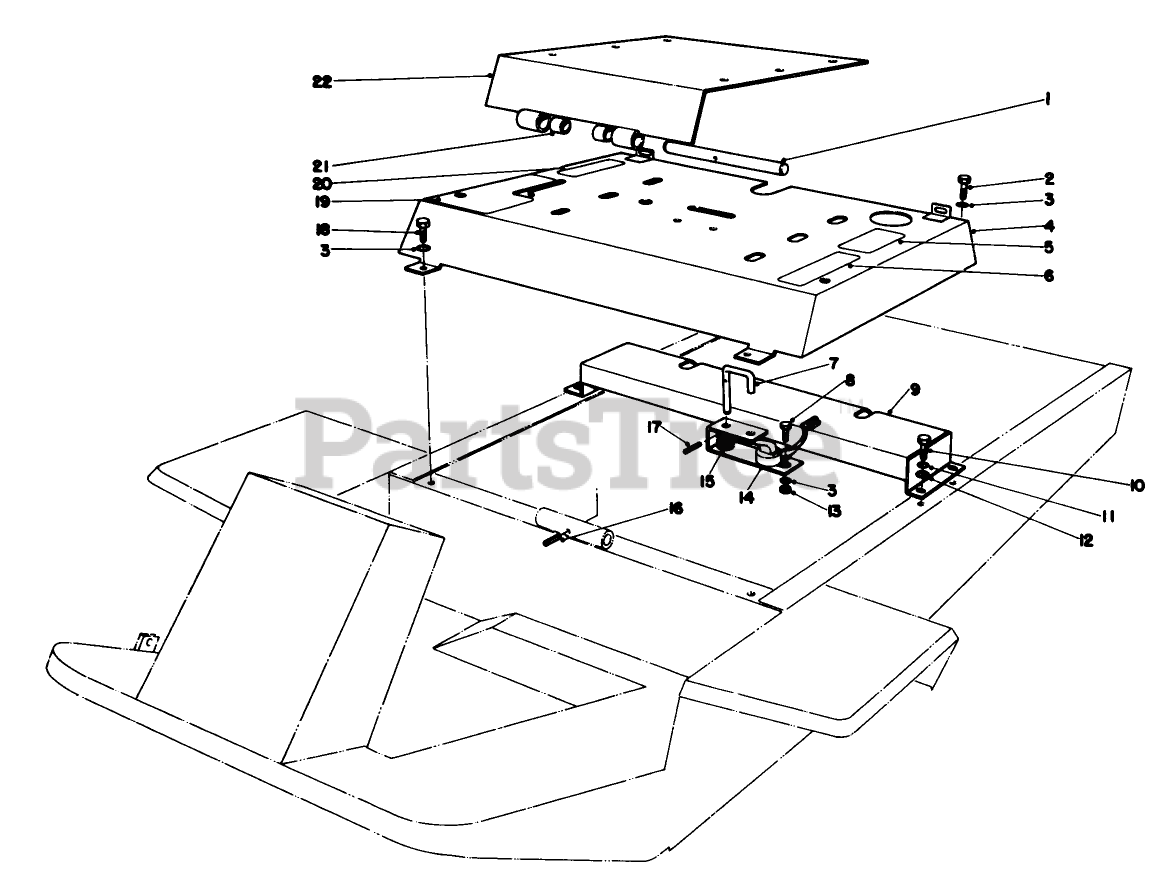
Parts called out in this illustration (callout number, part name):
1	SHAFT-PIVOT, SEAT
2	SCREW-HH
3	WASHER-LOCK
5	DECAL-REFUELING
8	SCREW-HH
10	SCREW-HH
11	WASHER-LOCK
12	WASHER-FLAT
13	NUT-HEX
14	SEAT SWITCH
15	SPRING
16	Pin-Roll
17	PIN-SPRING
18	SCREW THD 1/4 20 5/8
21	.503ID X .875LG BSHG
22	Seat Mount (Incl. Ref. #21)
